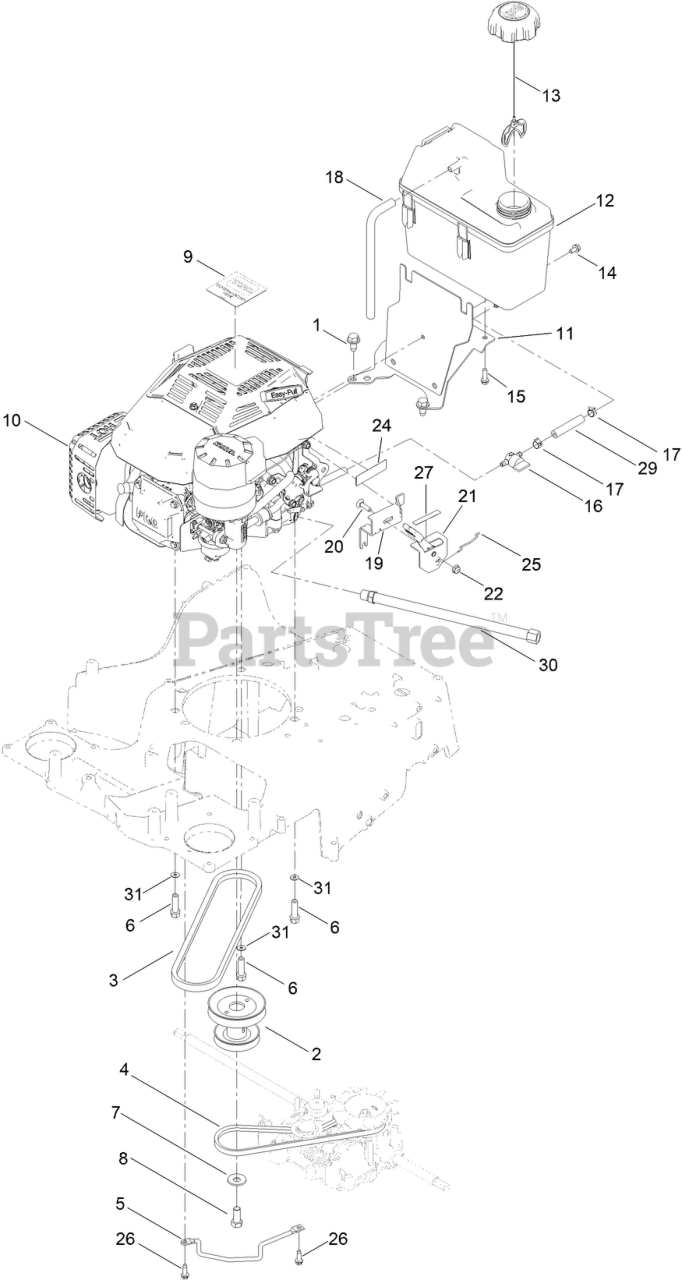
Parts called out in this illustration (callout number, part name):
1	SCREW-HWH
2	PULLEY-ENGINE
3	V-BELT
4	BELT-V
5	ROD-GUIDE, BELT
6	SCREW-TAPTITE
7	WASHER-BELLEVILLE
8	SCREW-HH
9	DECAL-TORO
11	TANK MOUNT ASM
12	TANK-FUEL
13	CAP-FUEL
14	SCREW-HWH
15	SCREW-HWH
16	VALVE-FUEL
17	CLAMP-HOSE
18	HOSE-VENT, CANISTER
19	BRACKET-THROTTLE
20	SCREW-CARR
21	CONTROL-THROTTLE
22	NUT-HF
24	DECAL-WARNING, ENGINE
25	WIRE-LINK
26	SCREW-HWHTF
27	DECAL-THROTTLE, CHOKE
29	HOSE-FUEL
30	HOSE-DRAIN, OIL
31	WASHER-LOCK
